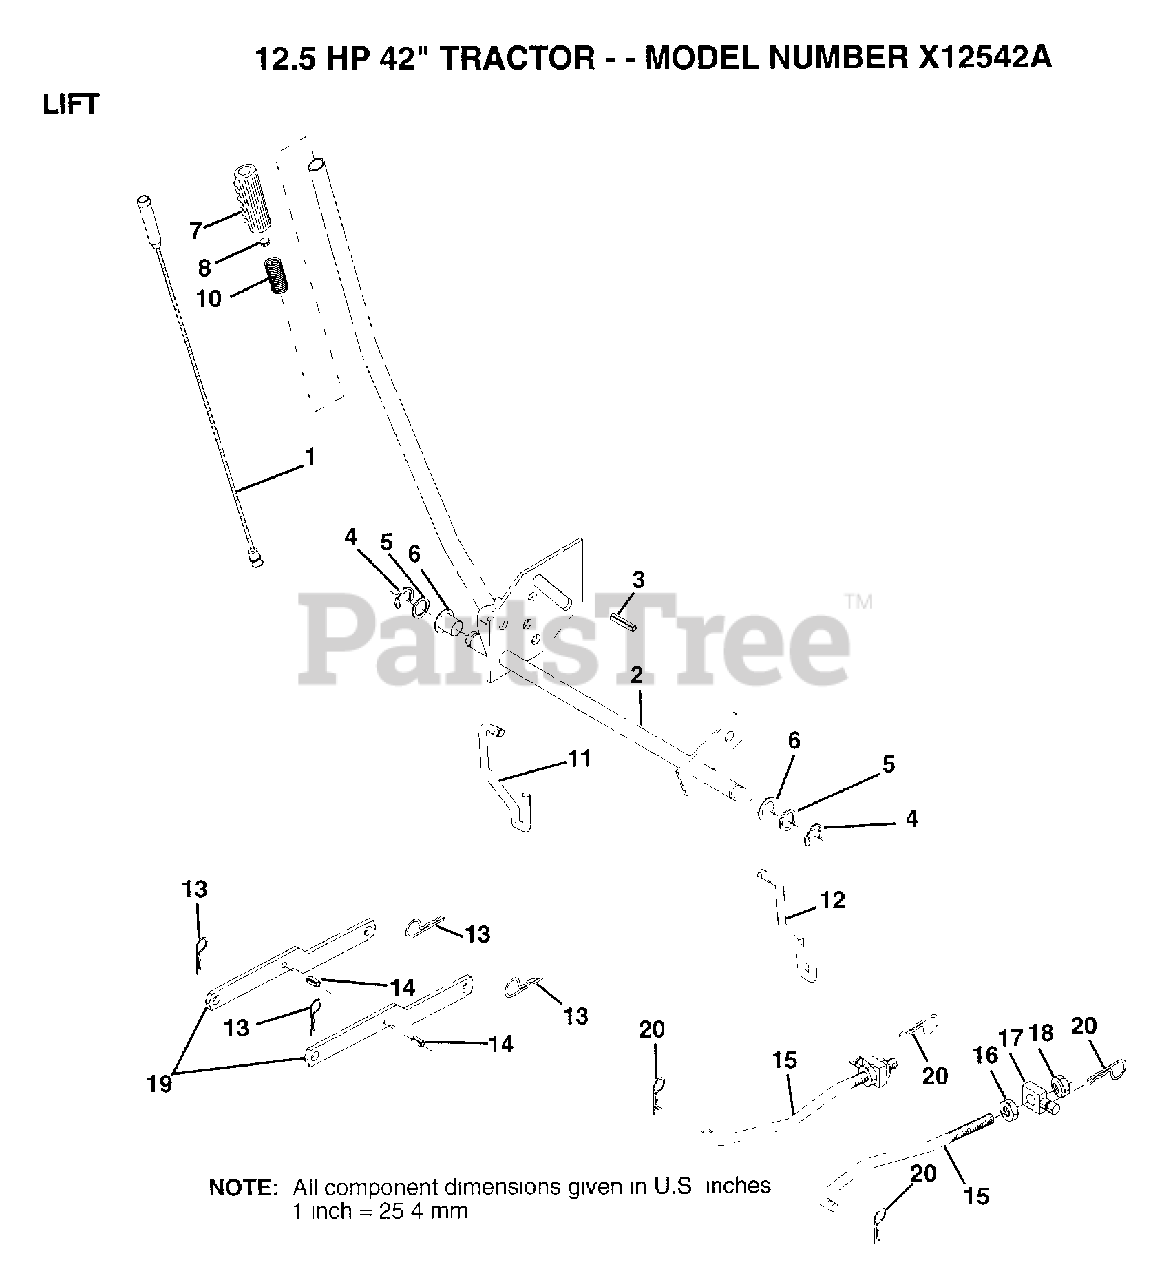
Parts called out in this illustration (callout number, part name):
1	WIRE ASM
3	PIN-GROOVE LT
5	WASHER
6	NYLON BEARING
7	GRIP
11	LINK LIFT LH
12	LIFT LINK RH
14	"PIN,SPRING"
15	LINK.FRONT
16	NUT
17	TRUNION
18	NUT.LK.W/WSH.1/2.
20	RETAINER.SPRING
